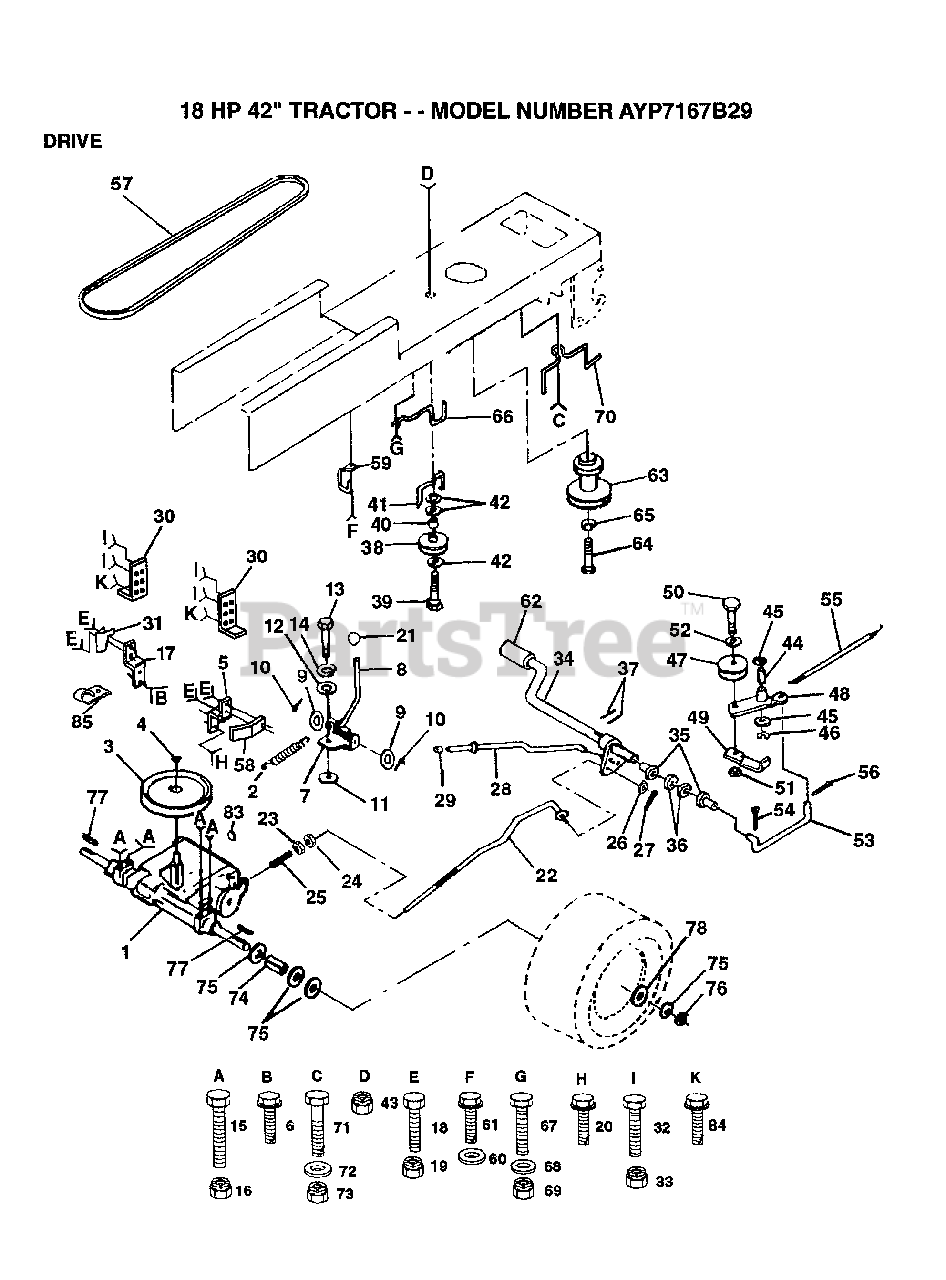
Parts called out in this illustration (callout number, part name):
3	"PULLEY,TRANSAXLE"
5	STRAP TORQUE
6	SCREW
8	SHIFT ROD
9	WASHER
10	PIN COTTER 1/8
11	WASH-SHFT PLT LT
12	WASHER LT
14	LOCKWASHER
15	BOLT
17	STRAP TORQUE
20	SCREW
21	KNOB T (1/2-HOLE)
22	BRAKE ROD
23	NUT
24	NUT
25	SPRING ROD LT
26	WASHER
27	COTTER PIN
28	BRAKE PARK ROD
29	PLUNGER CAP T
30	TRANSAXLE MTG BKT
31	"KEEPER,BELT LH"
32	BOLT
35	NYLON BEARING
36	WASHER LT
38	PULLEY.IDLER.FLAT
39	BOLT
40	SPACER T
41	BELT KEEPER LT
42	WASHER
44	"LY, BEARING"
45	WASHER LT
46	KLIP RING
48	ARM IDLER
49	RETAIN BELT
52	WASHER
53	"LINK, CLUTCH T"
54	COTTER PIN
55	"SPRING, RETURN LT"
56	COTTER PIN
57	BELT-V
58	"KEEPER,BELT RH"
60	WASHER
61	SCREW
62	PEDAL COVER T
64	BOLT
65	LOCKWASHER
66	KEEPER.BELT.ENG.L
67	BOLT
68	WASHER
70	KEEPER BELT ENG
71	BOLT
72	WASHER
74	SPACER LT
75	WASHER
76	E-RING LT
77	SQUARE KEY
78	WASHER
84	SCREW
85	CLIP T
